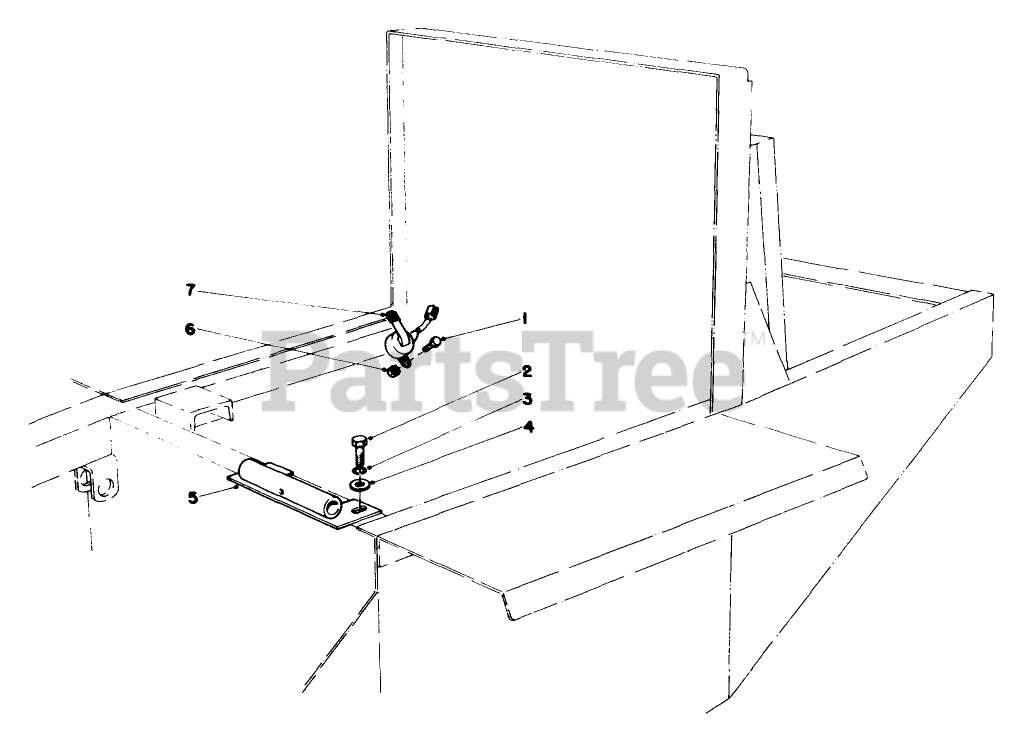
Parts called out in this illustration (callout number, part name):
1	SCREW-HH
2	SCREW-HH
3	WASHER-LOCK
4	WASHER-PLAIN
5	Pivot-Seat
6	NUT-LOCK, NI
7	SWITCH ARM
